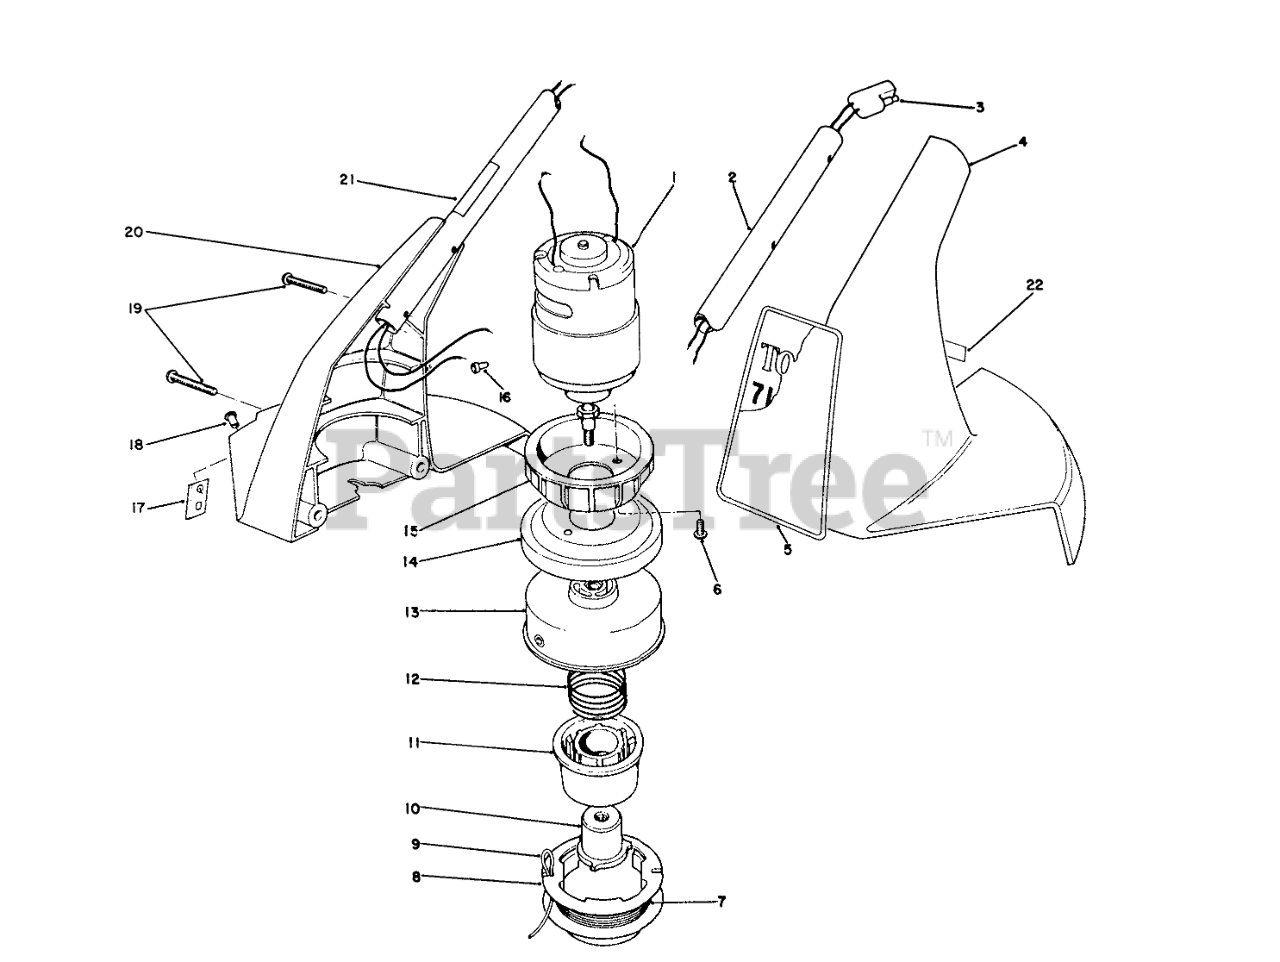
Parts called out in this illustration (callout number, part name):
1	MOTOR ASM
2	EXTENSION HANDLE
3	WIRING HARNESS LOWER
4	Housing-L.H.
5	710 HOUSING DECAL
6	SCREW
7	Cutting Line (12- .05 Dia.)
8	CAP-SPOOL
9	Cutting Line (30- .05 Dia.)
10	DRIVER
11	CORE - SPOOL
12	Spring
13	Drum w/Eyelet
14	DRUM CUP
15	Casting-Heat Sink
16	Connector
17	Knife Blade
18	Rivet
19	SCREW-PLASTITE
20	R.H. Motor Housing (Incl. Ref. #17 & 18)
21	REP. SERIAL PLT
22	Decal
